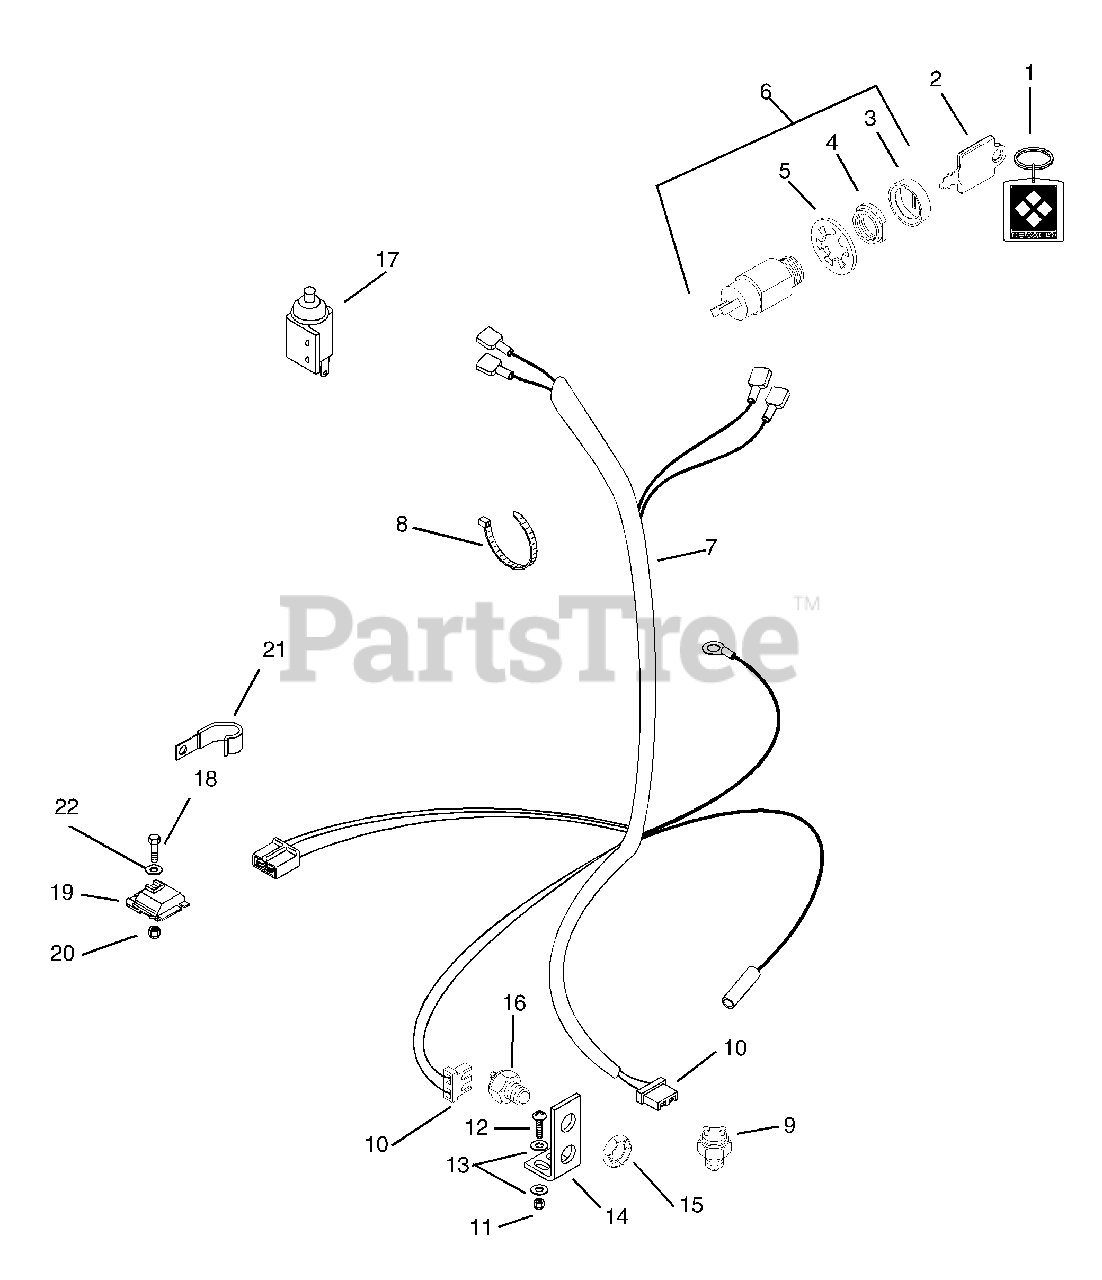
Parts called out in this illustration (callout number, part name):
1	Key Chain
2	Ignition Switch Key
3	Cap-Ignition Switch
4	Nut-Panel .625-32
5	Washer-Lock-Internal .625 x .045
6	Key Switch Assembly
7	Harness, Wiring Pro Recoil
8	Tie Wrap, Black
9	Switch-Neutral Start N.C.
10	Connector, 2-Wire Switch
11	Nut-Locking 10-24
12	Screw-Machine 10-24 x .750
13	Washer-Flat-Steel .219 x ..50 x .049
14	Bracket, Interlock Switch
15	Nut, Stamped .56-18
16	Switch-Neutral Start
17	Single Pole N.O. with Cover
18	Bolt-Hex .25-20 x .75 Grade 5
20	Nut-Locking-Center .250-20
22	Washer-Flat-Steel .344 x .688 x .065
